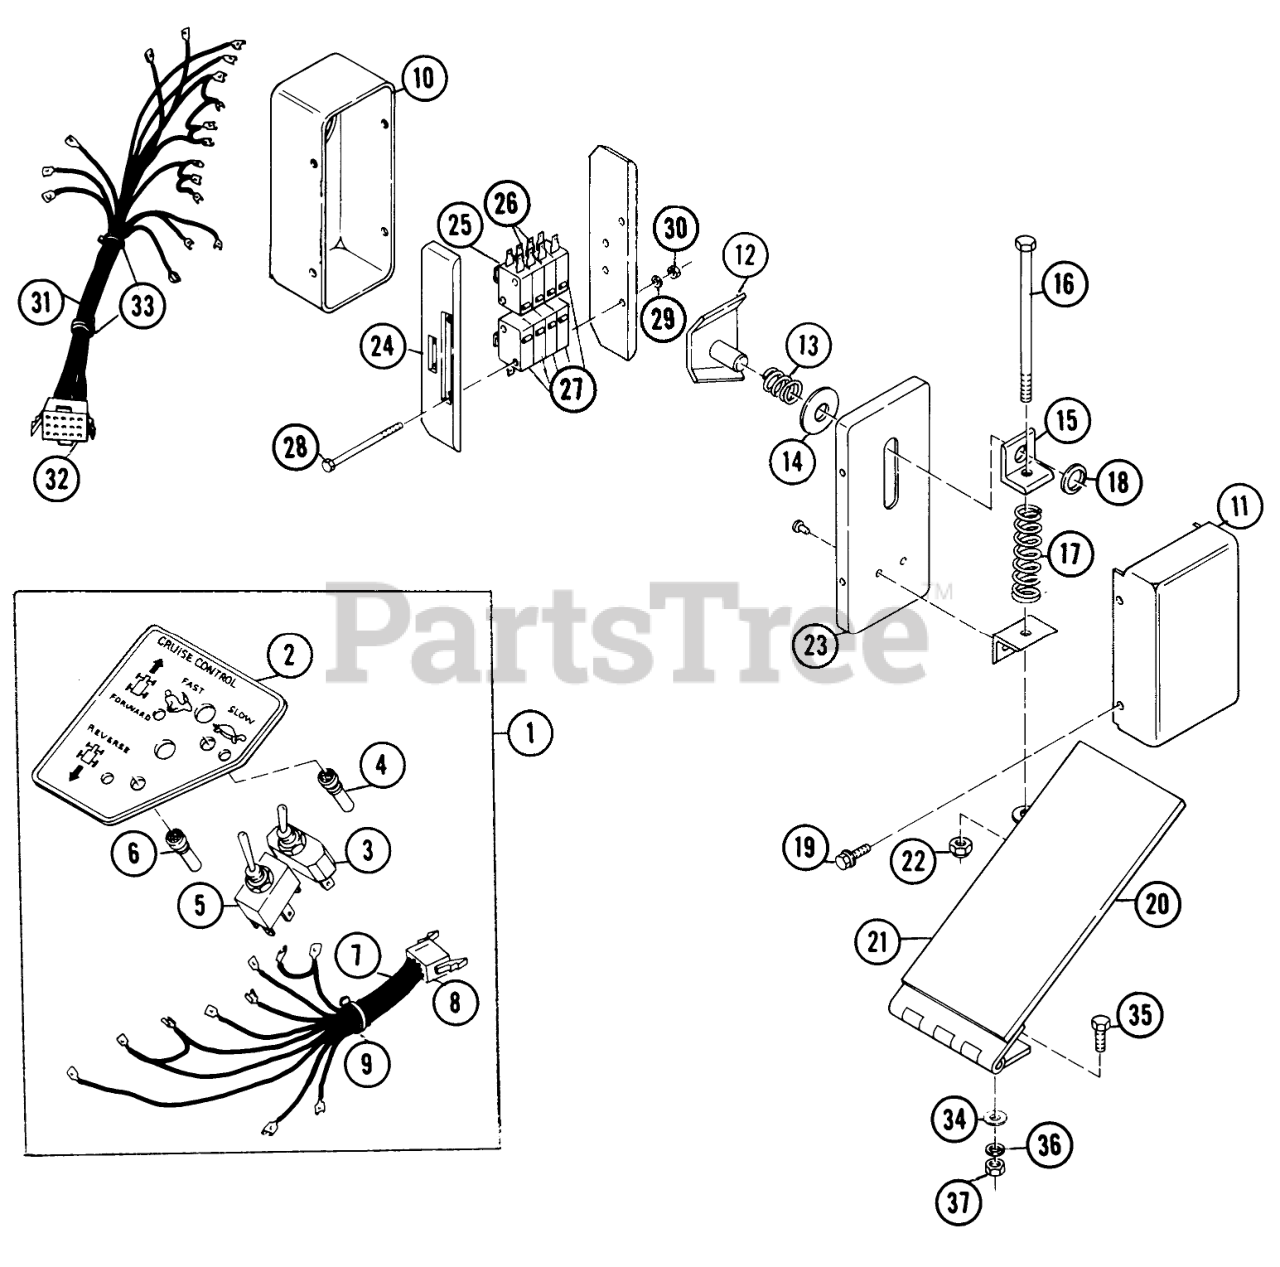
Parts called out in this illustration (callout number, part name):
10-01	Forward-Reverse Panel Assembly
10-02	Plate, Forward-Reverse
10-03	Light Switch
10-04	Cruise Control Light (Green)
10-05	Forward--Reverse Switch
10-06	Reverse Light (Red)
10-07	Forward-Reverse Control Harness
10-08	Socket Housing
10-09	Cable Tie
10-10	Box, Throttle
10-11	Cover, Throttle
10-12	Cam Assembly
10-13	Spring
10-14	Washer 3/8 Brass
10-15	Angle
10-16	Screw, Hex 1/4-20 x 4 1/2
10-17	Spring
10-18	Push Nut
10-19	Screw, Hex #6-32 x 3/8
10-20	Pedal Assembly (w/Pad)
10-21	Pad, Throttle Pedal
10-22	Locknut, 1/4-20
10-23	Cover & Bracket Assembly
10-25	Switch, Start
10-26	Switch, 1A, 2A
10-27	Switch, (SW-4,FWS-1,FWS-2,FWS-3,FWS-4)
10-28	Screw, Fillister Hd. #4-40 x 2-1/16
10-29	Spring Lockwasher #4
10-30	Nut, Hex #4-40
10-31	Throttle Harness
10-32	Socket Housing
10-33	Cable Tie
10-34	Washer 5/16
10-35	Screw, 5/16-18 x 3/4
10-36	Lockwasher-5/16
10-37	Cotter Pin
